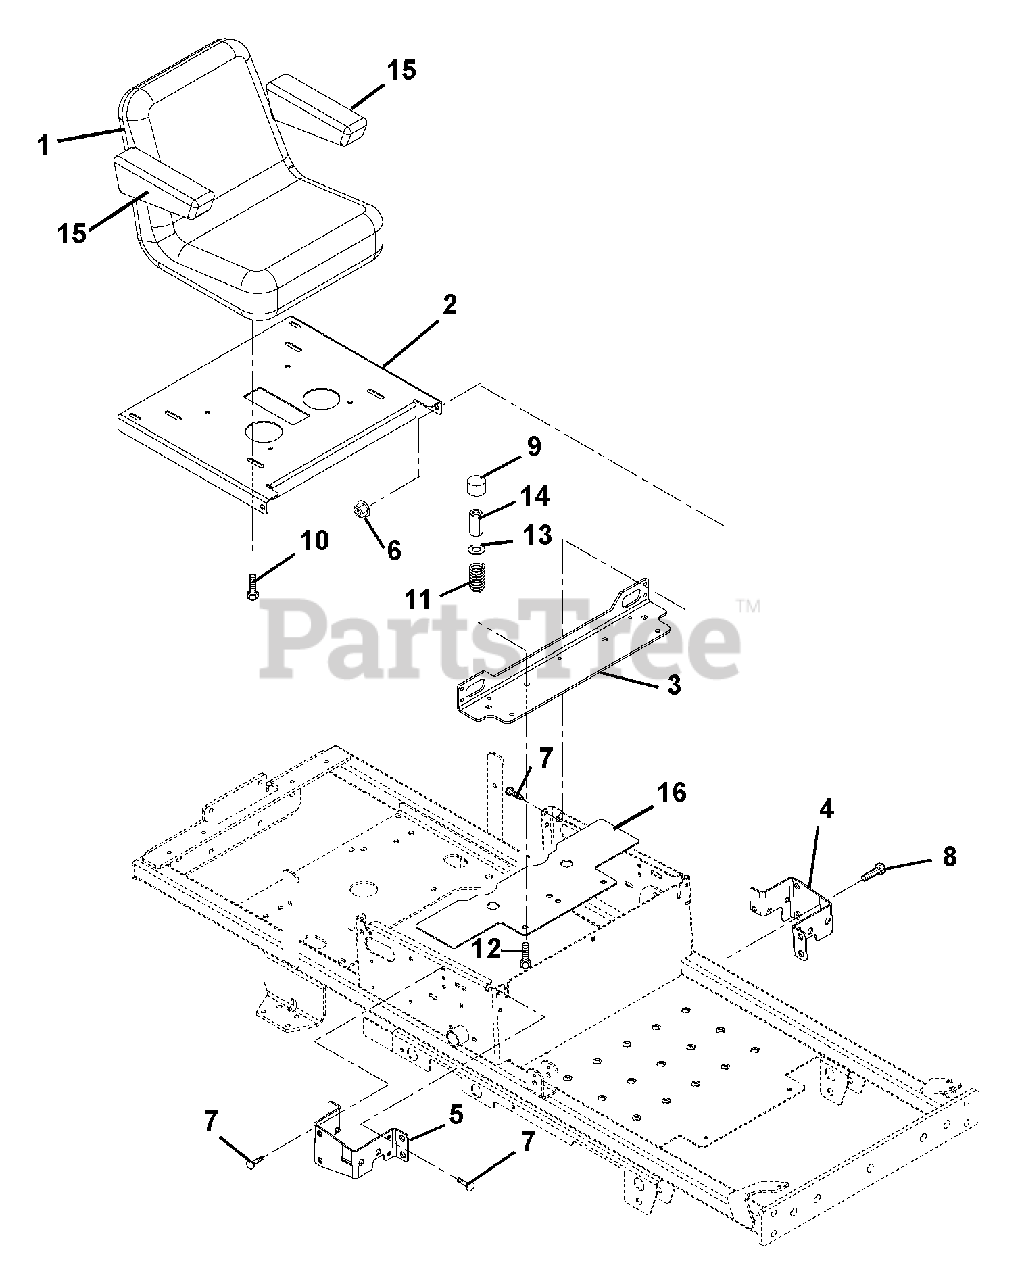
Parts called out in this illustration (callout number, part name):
1	SEAT,V-2505 MICHIGAN W/ARM
2	SEAT PLATE
3	BRKT, SEAT SPRING
4	WDMT, RH STEERING STOP
5	WDMT, LH STEERING STOP
6	@NUT-LK-TOP-FLG .38-16 YWZC
7	@SCR-TAP .31-18X.50 HWH TR YWZ
8	BOLT-SHLDR .375-16X.150
9	HUB CAP
10	5/16-18X3/4 HX/W/HD WHIZ
11	SPRING, SEAT
12	@BLT-RDHDSQNK .31-18X1.50 G5YZ
13	WSHR-FL-STL .328X.87X.179 YWZC
14	NUT, COUPLING 5/16-18 X 1 3/4
15	KIT,ARMREST PAD ONLY 1 PER KIT
16	GUARD, ZOOM FINGER
